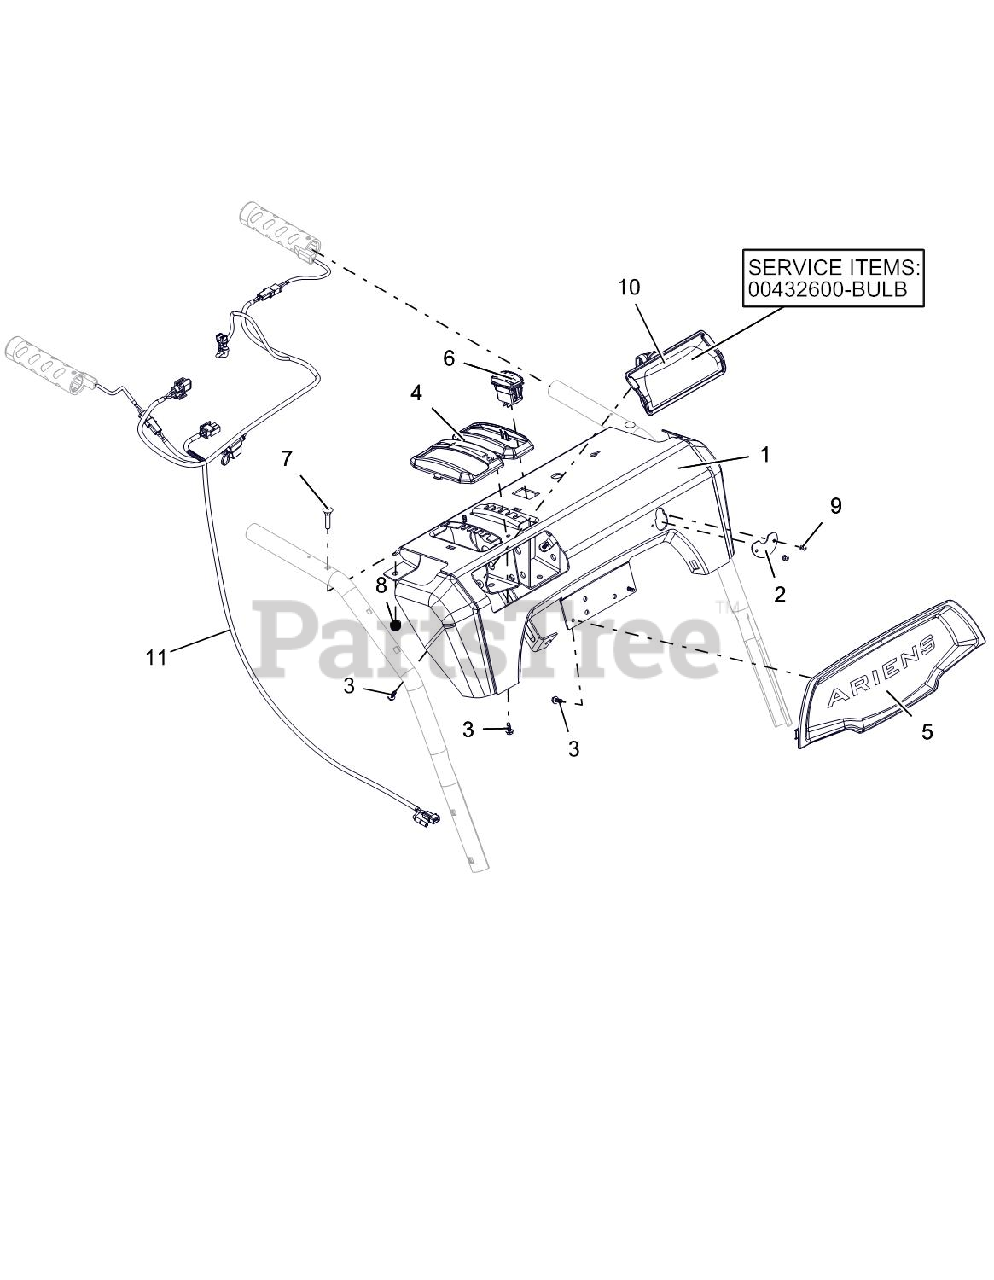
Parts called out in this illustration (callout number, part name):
1	PANEL, CONTROL-EFI ID W/DECAL
2	COVER, DASH BRKT, ID
3	SCR-TAP #10X.50 BOSS INDHXHD
4	BEZEL, SHIFT - FRICTION SNOW
5	BEZEL, DASH - ARIENS LG DASH
6	SWITCH,ROCKER SPST-ON/OFF
7	BLT-RDHDXLSQNK.25-20X1.25 G5ZC
8	@NUT-LK-CTR-FLG .25-20 YWZC
9	RVT-POP #43 .125X.313 STL ZINC
10	BULB, LIGHT-HALOGEN 20W
10	HEADLIGHT ASY, HALO 20W 2SHOT
11	HARNESS,LIGHT&WARMER - EFI
